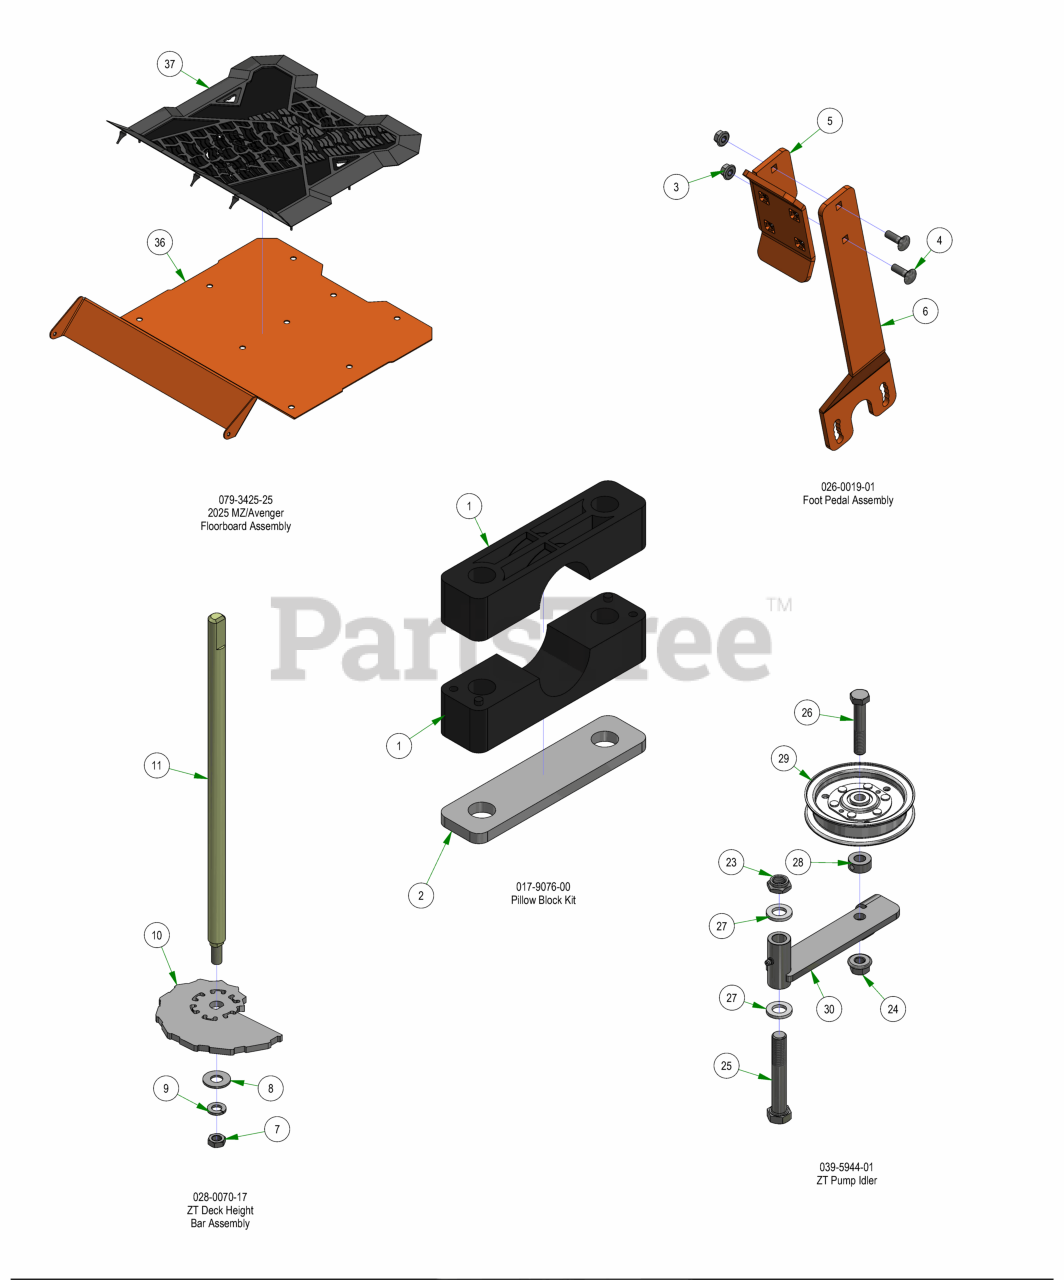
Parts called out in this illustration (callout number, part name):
1	Pillow Block MZ
2	Pillow Block Strap
3	5/16-18 NYLON INSERT FLANGE LOCKNUT ZINC
4	5/16-18 X 1 CARRIAGE BOLT (GR.8) ZINC
5	2017 MZ/ZT Shallow Foot Pedal
6	2017 MZ/ZT Deck Pedal Lever
7	3/8-24 HEX NUT ZINC YELLOW
8	3/8 FLAT WASHER USS (1" OD) ZINC
9	3/8 SPLIT LOCKWASHER ZINC
10	2017 MZ/ZT Cam Plate
11	2017 Deck Height Dial Rod ZT
12	3/8-16 Half Jam Nut
13	3/8-16 HEX SERRATED FLANGE NUT HARD/ZINC
14	3/8-16 X 2 HEX CAP SCREW (GR.5) ZINC
15	3/8 FLAT WASHER USS (1" OD) ZINC
16	Seat Spring
17	3/8-16 Half Jam Nut
18	3/8-16 HEX SERRATED FLANGE NUT HARD/ZINC
19	3/8-16 X 2 HEX CAP SCREW (GR.5) ZINC
20	3/8 FLAT WASHER USS (1" OD) ZINC
21	Seat Spring
22	Seat Strap with Buckles
23	5/8-11 NYLON INSERT JAM LOCKNUT ZINC
24	1/2-13 NYLON INSERT FLANGE LOCKNUT ZINC
25	5/8-11 X 4 HEX CAP SCREW (GR.8) ZINC YELLOW
26	1/2-13 X 2-3/4 HEX CAP SCREW (GR.5) ZINC
27	.635 ID X 1.120 OD X .140 THICK FLAT WASHER NYLON
28	1/2 SOLID SHAFT COLLAR (W/1 SET SCREW) ZINC
29	4 3/4" Idler Pulley
30	Pump Idler Bracket
31	Seat Cover for 071-1000-00
32	Seat Foam for 071-1000-00
33	SeatSwitch for 071-1000-00/071-1000-22/071-2100-22
34	Avenger Seat Cover
35	Water Proofing Protection
36	2025 MZ Avenger Floorboard
37	25 Mav Floor Mat. V4
38	Tachometer
39	10-24 Nylon Insert Locknut Zinc Orange Nylon
40	Light Plug
41	10-24 X 5/8 BS Button Head Bolt
42	Throttle Lever Assembly
43	PTO Engager
44	4-Way Key Switch
45	2025 Control Panel
46	2025 Reaper Control Panel Decal
47	Relay Block Cover Replacement Kit
